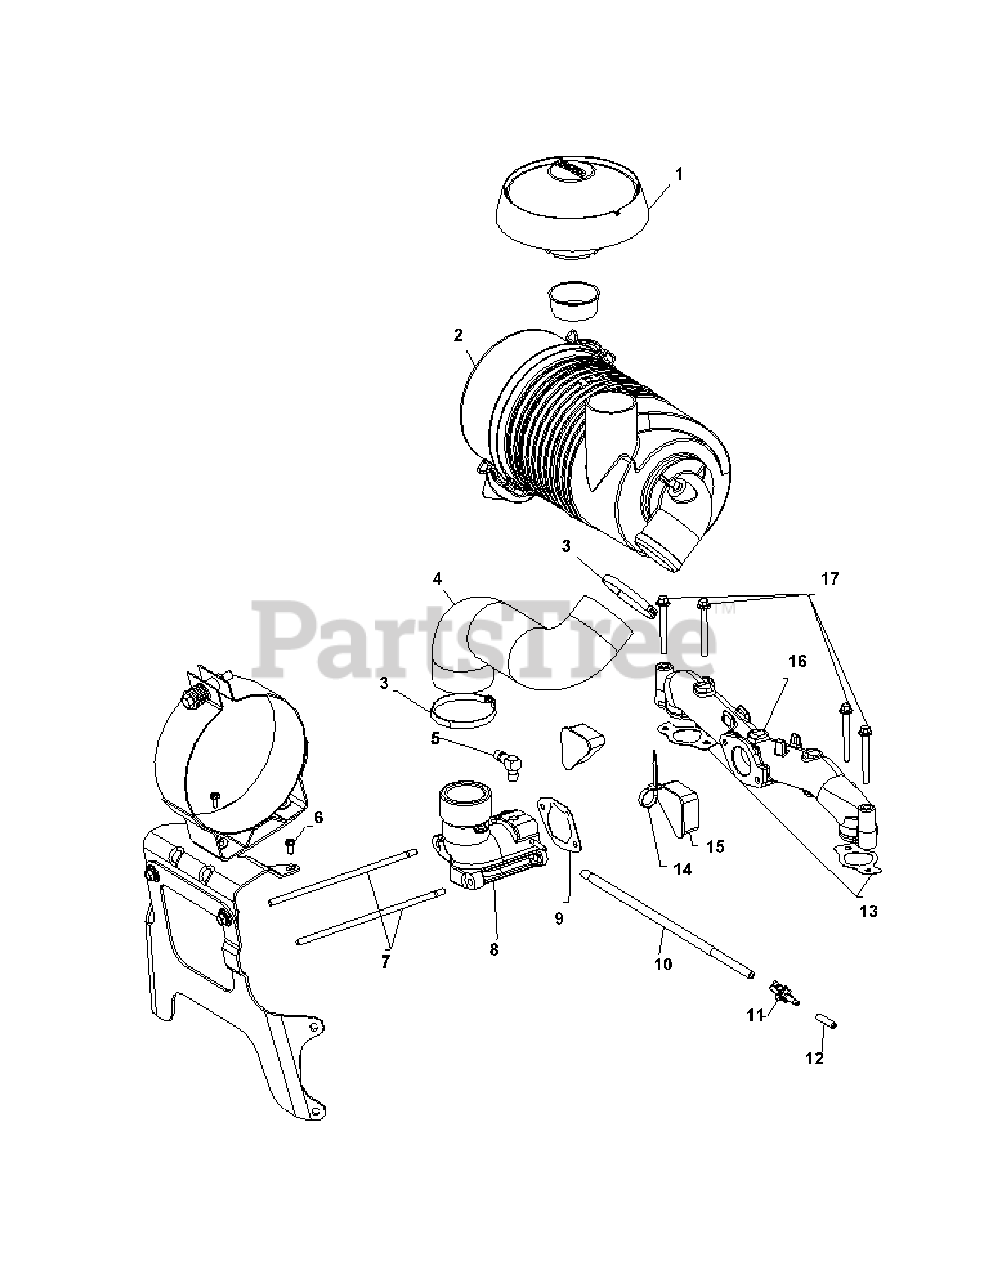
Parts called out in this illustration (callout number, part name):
4	Air Cleaner Hose
5	Hose Connecter
6	Screw, #8-18 x 1/2
7	Stude, M6 x 1.0 x 180
9	Air Cleaner Base Gasket
10	Evaporative Hose
11	Evaporative Connector
13	Intake Manifold Gasket
15	Blower Housing Cover
16	Intake Manifold
17	Screw, M6 x 1.0 x 55
